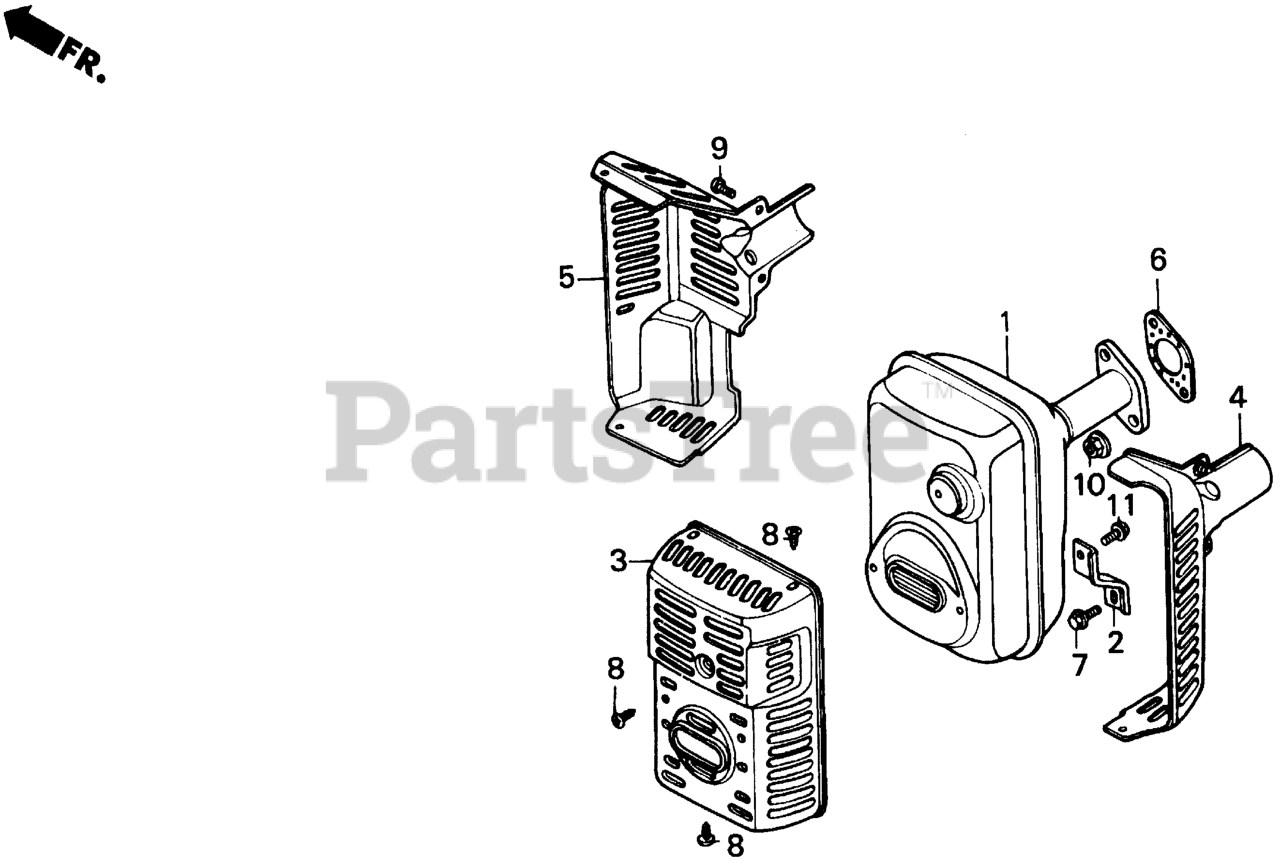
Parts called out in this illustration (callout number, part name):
1	MUFFLER
2	STAY, MUFFLER
3	PROTECTOR, FR. MUFFLER
4	PROTECTOR, R. MUFFLER
5	PROTECTOR, L. MUFFLER
6	GASKET, MUFFLER
7	BOLT, FLANGE (6X12) (CT200)
8	SCREW, TAPPING (4X8)
9	SCREW, PAN (4X6) Use from Engine SN 1012895 to 1428861.
10	NUT, FLANGE (8MM)
11	BOLT, FLANGE (6X10)
